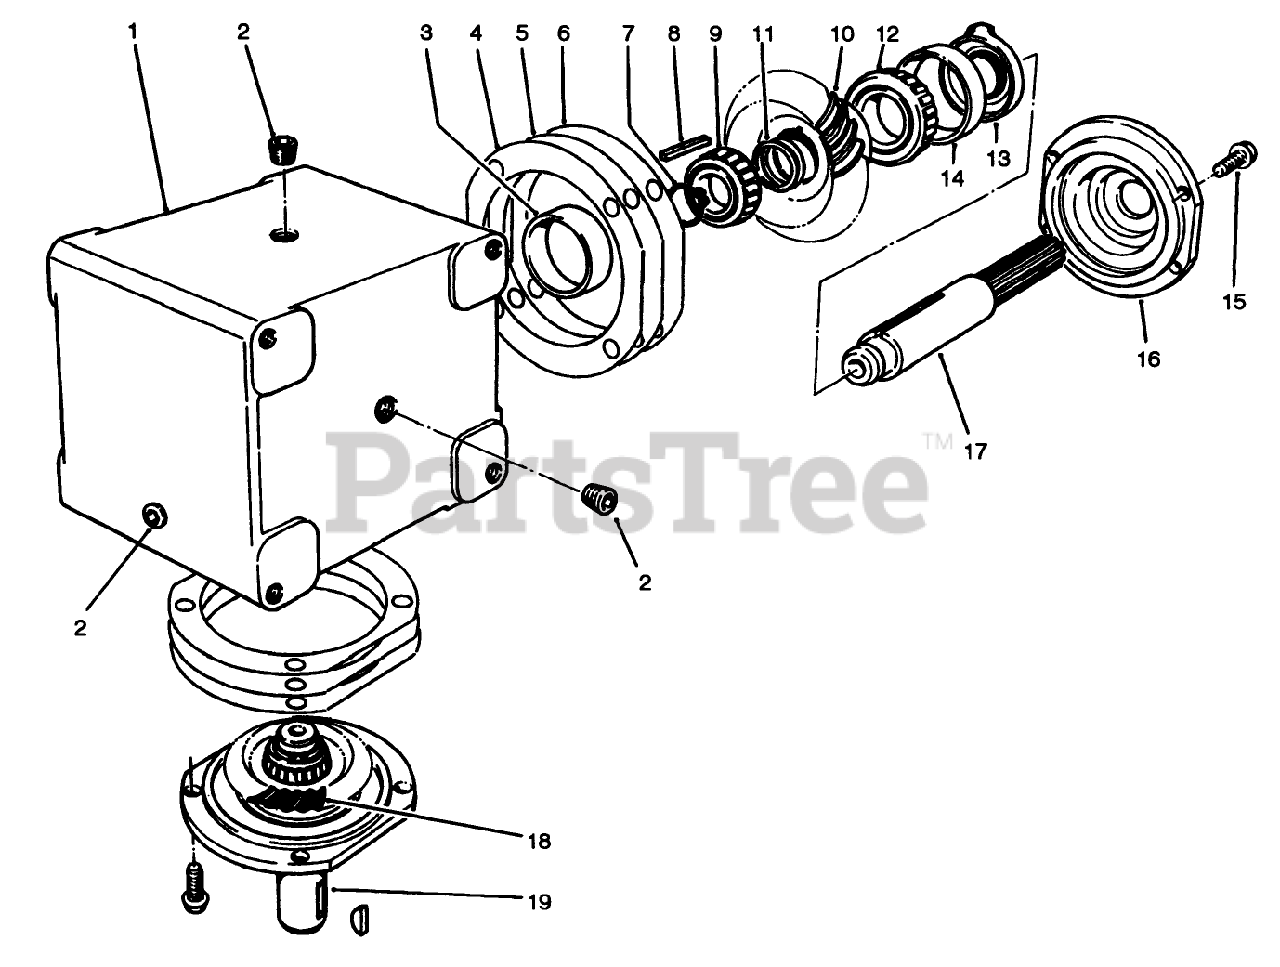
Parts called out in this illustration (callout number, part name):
1	HOUSING
2	PLUG (OBS, C/R TO 281-10)
3	Bearing Cup
4	GASKET
5	GASKET
6	GASKET
7	Ring-Retaining
8	Key
9	Cone
12	Cone
13	Seal
14	Cup
15	SCREW-HH (OBS, C/R TO 3234-5)
17	Shaft
19	Shaft
